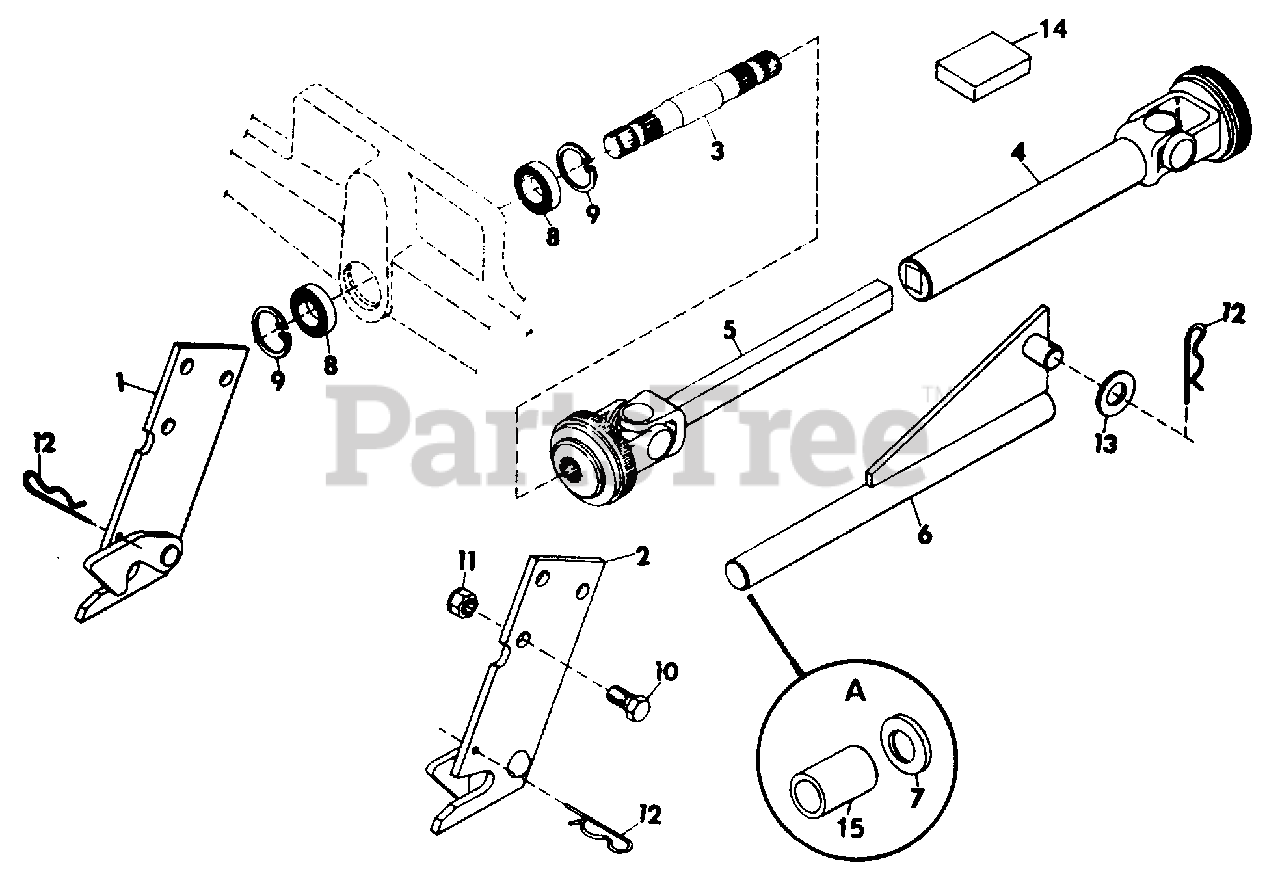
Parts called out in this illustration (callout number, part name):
1	BRACKET, FRONT ATTACHMENT WELD, R.H.
2	BRACKET, FRONT ATTACHMENT WELD, L.H.
3	SHAFT, FRT PTO
4	SHAFT, FRT PTO PROP.
5	JOINT, U, MALE END
6	GUIDE, PUSH ROD WELDMENT
7	WASHER, FLAT 1.062X2.000X.134
8	BEARING, BALL .984X2.047X.590
9	RING, RETAINING 2.062X.590
10	BOLT, HEX 1/2-13X1
11	NUT, HEX 1/2-13
12	PIN, HAIR
13	WASHER, FLAT .812X1.496X.134
14	KIT, REPAIR UNIVERSAL JOINT(NEAPCO)
15	SPACER
